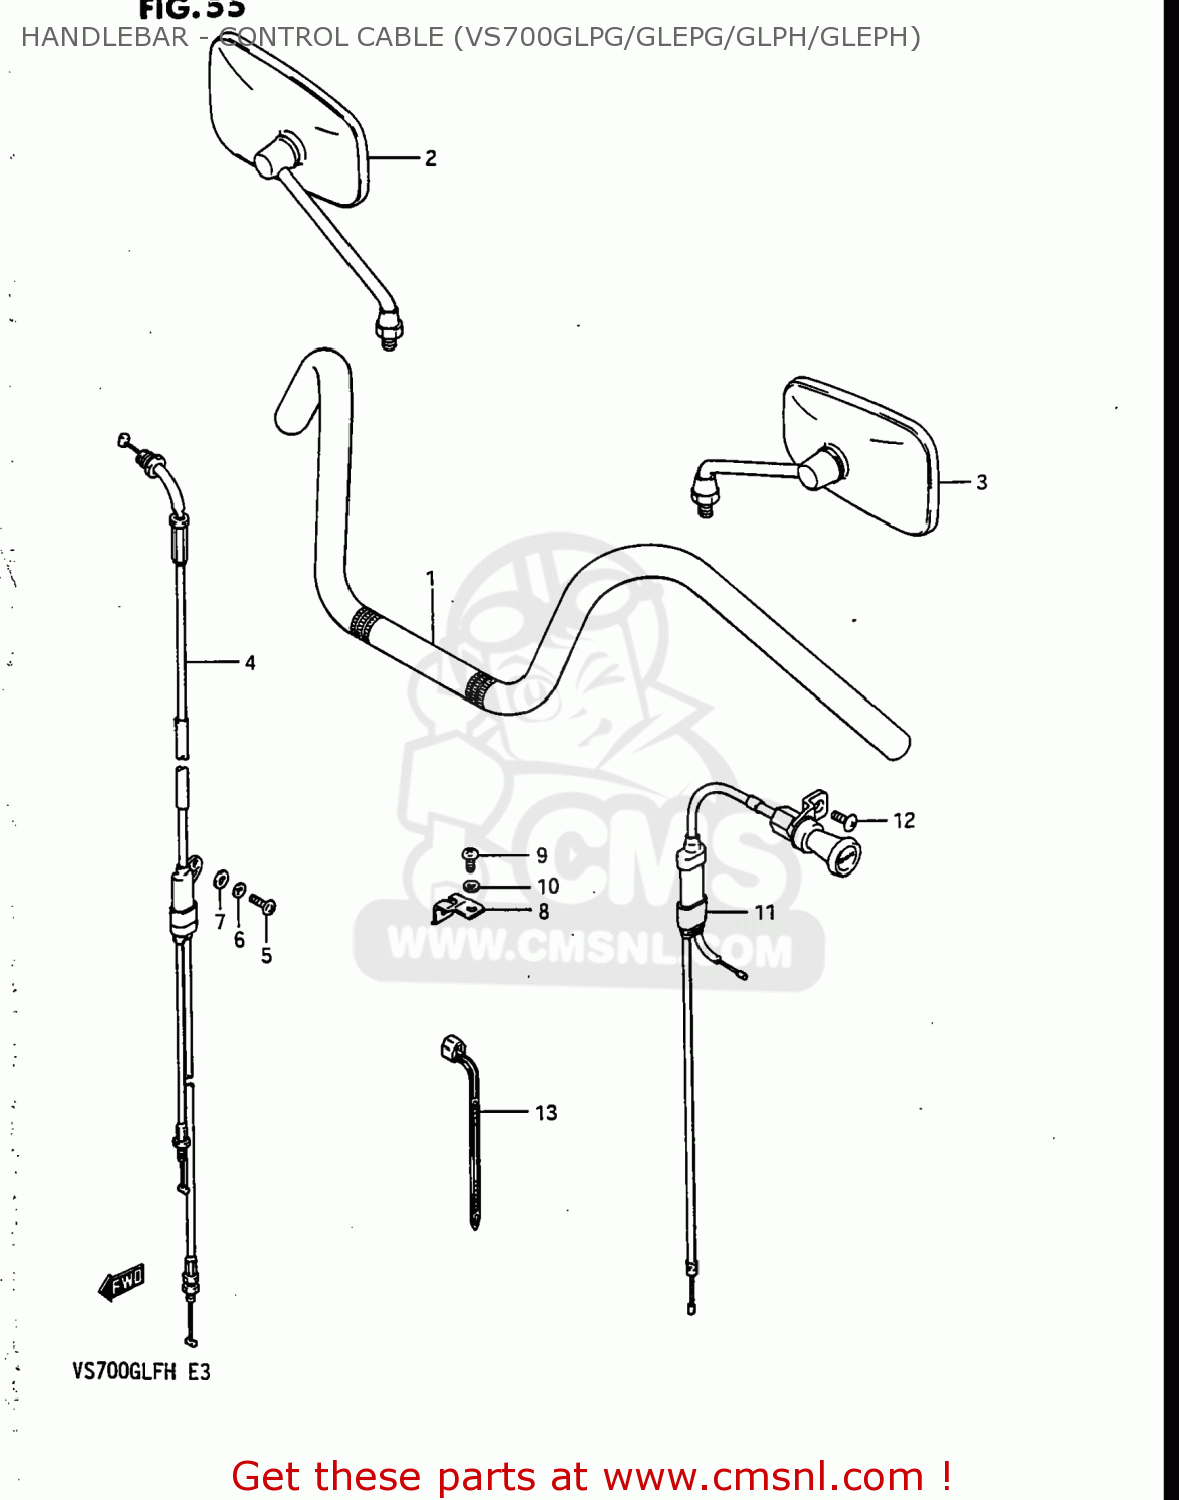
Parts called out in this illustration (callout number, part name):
1	HANDLEBAR,RIGHT
2	MIRROR ASSY,RR VIEW,R
3	MIRROR ASSY,RR VIEW,L
4	CABLE ASSEMBLY,THROTTLE
5	SCREW
6	LOCK WASHER
7	WASHER
8	CLAMP,THROTTLE CABLE
9	SCREW
10	LOCK WASHER
11	CABLE ASSEMBLY,STARTER
12	SCREW
13	CLAMP(L:125)
